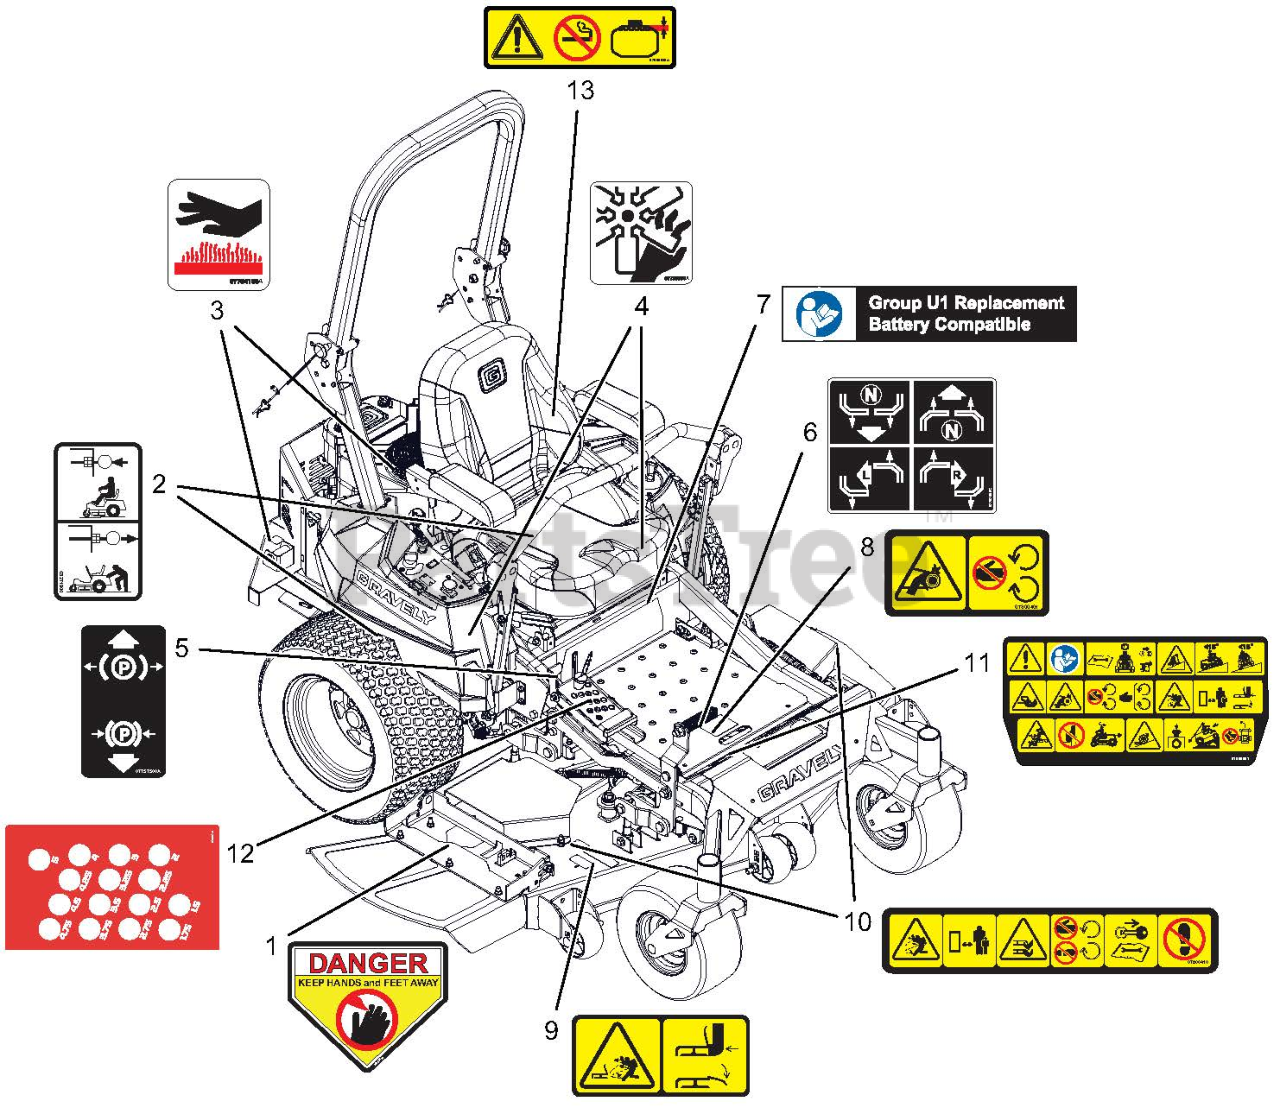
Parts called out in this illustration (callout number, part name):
1	DECAL, DANGER
2	DECAL, TRANSMISSION DISCONNECT
3	DECAL, HOT SURFACE
4	DECAL, DANGER FAN
5	DECAL, PARKING BRAKE LEVER
6	DECAL, INSTRUCTIONAL-STEERING
7	DECAL, U1 BATTERY REPLACEMENT
8	DECAL, SAFETY - GUARDING
9	DECAL, SAFETY - DECK GUARDING
10	DECAL, DECK SAFETY
11	DECAL, MAIN SAFETY
12	DECAL - HOC
13	DECAL, FUEL WARNING
